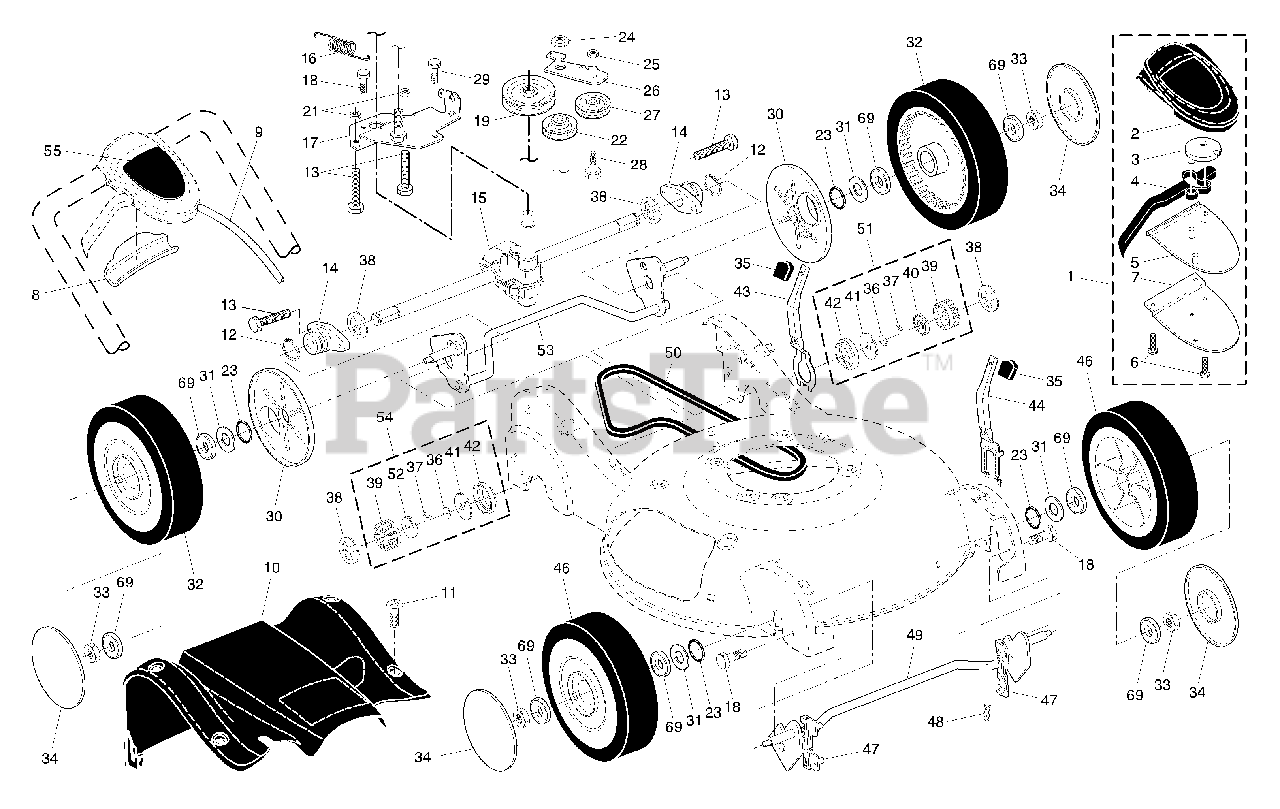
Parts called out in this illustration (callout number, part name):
1	Drive Control Assembly, Complete
2	Cover, Drive Control, Top
3	Pulley, Drive Control
4	Lever, Drive Control (blue)
5	Cover, Drive Control, Bottom
6	Screw, Torx Head #8-5/8
7	Bracket, Mounting, Drive Control
8	Cap, Drive Control, Bottom
9	Cable, Drive Control
10	Cover Assembly, Drive
12	Ring, Retaining
14	Bearing / Axle Support
15	Gear Case Assembly
16	Spring, Return
17	Bracket, Gear Case / Drive Pulley
18	Screw
19	Pulley, Drive
21	Nut, Hex
22	Pulley Assembly, VGroove
24	Nut, Hex, Flangelock
25	Nut, Hex, Lock
26	Idler Arm
27	Pulley, Idler
28	Bolt, Hex Head, Shoulder
29	Screw 1/4-20 x 1-1/16
30	Cover, Dust, Wheel
31	Washer, Flat 3/8
32	Wheel Assembly, Rear 9 x 2-1/4
33	Nut, Hex
34	Hubcap
35	Knob
36	Spring, Torsion
37	Pawl
38	ERing
39	Gear
40	Retainer, Drive, LH
41	Disc, Drive
42	Seal, Friction
43	Lever, Selector, Wheel Height, Rear
44	Lever, Selector, Wheel Height, Front
45	Screw
46	Wheel Assembly, Front 9 x 2-1/4
47	Bushing, Front Axle
48	Retainer, Hairpin Cotter
49	Torque Shaft Assembly, Front
50	Belt, Drive
51	Pinion Assembly, LH
52	Retainer, Drive, RH
53	Rear Axle Assembly
54	Pinion Assembly, RH
55	Decal, Drive Control
69	Bearing, Ball (Wheel)
